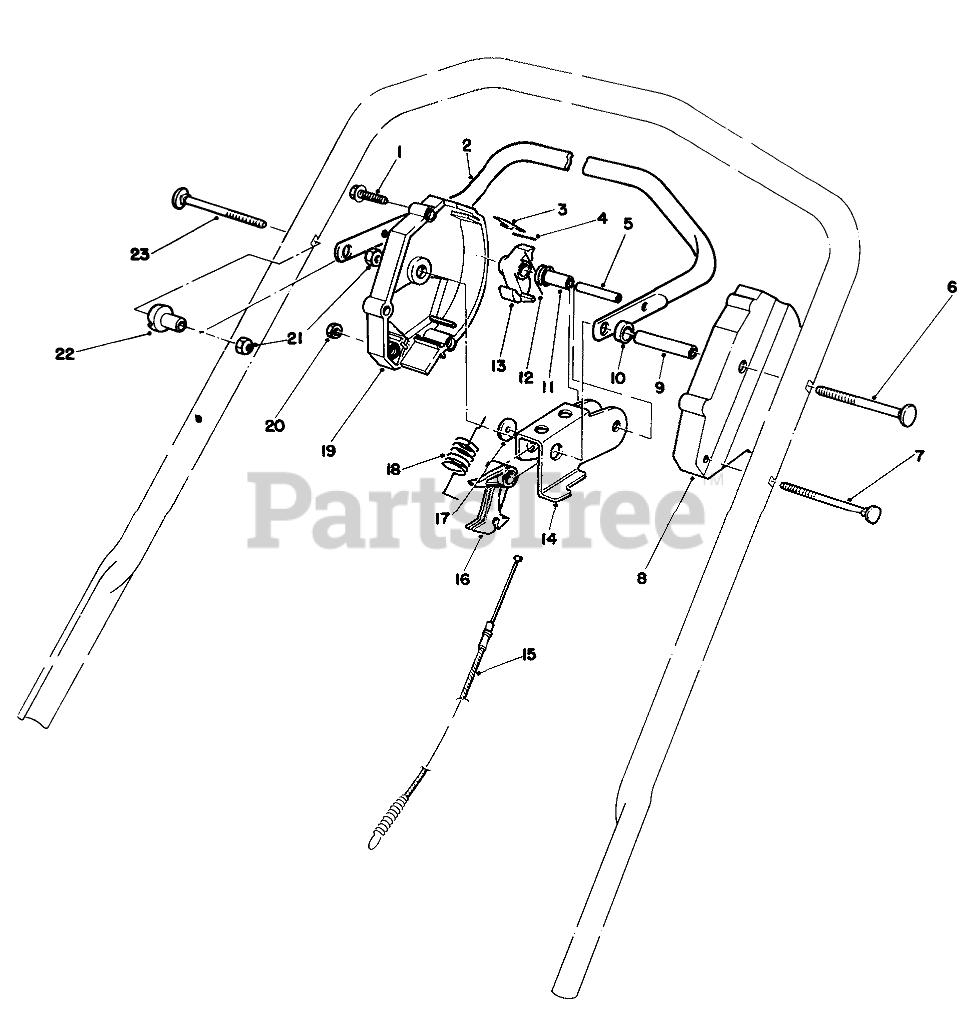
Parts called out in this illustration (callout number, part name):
1	SCREW-HWHTF
2	Bar-Control
3	SPRING-LEAF
4	PIN-INSERT
5	PIN-ROLL, SLOTTED
6	5/16-18 X 3 HNDLE SCREW
7	HANDLE SCREW
8	HOUSING-CONTROL, LH
9	TUBING-SPACER
10	SPACER-NYLON
11	Bushing-P.M.
12	SPRING-TORSION
13	HOOK-CONTROL
14	Rocker
15	Cable-Clutch
16	LEVER-CABLE
17	PLASTIC WASHER
18	Spring-Detent
19	Housing Control R.H.
20	NUT-LOCK, NI
21	NUT-LOCK, NI
22	SPACER-SUPPORT
23	5/16-18 X 2 HNDLE SCREW
